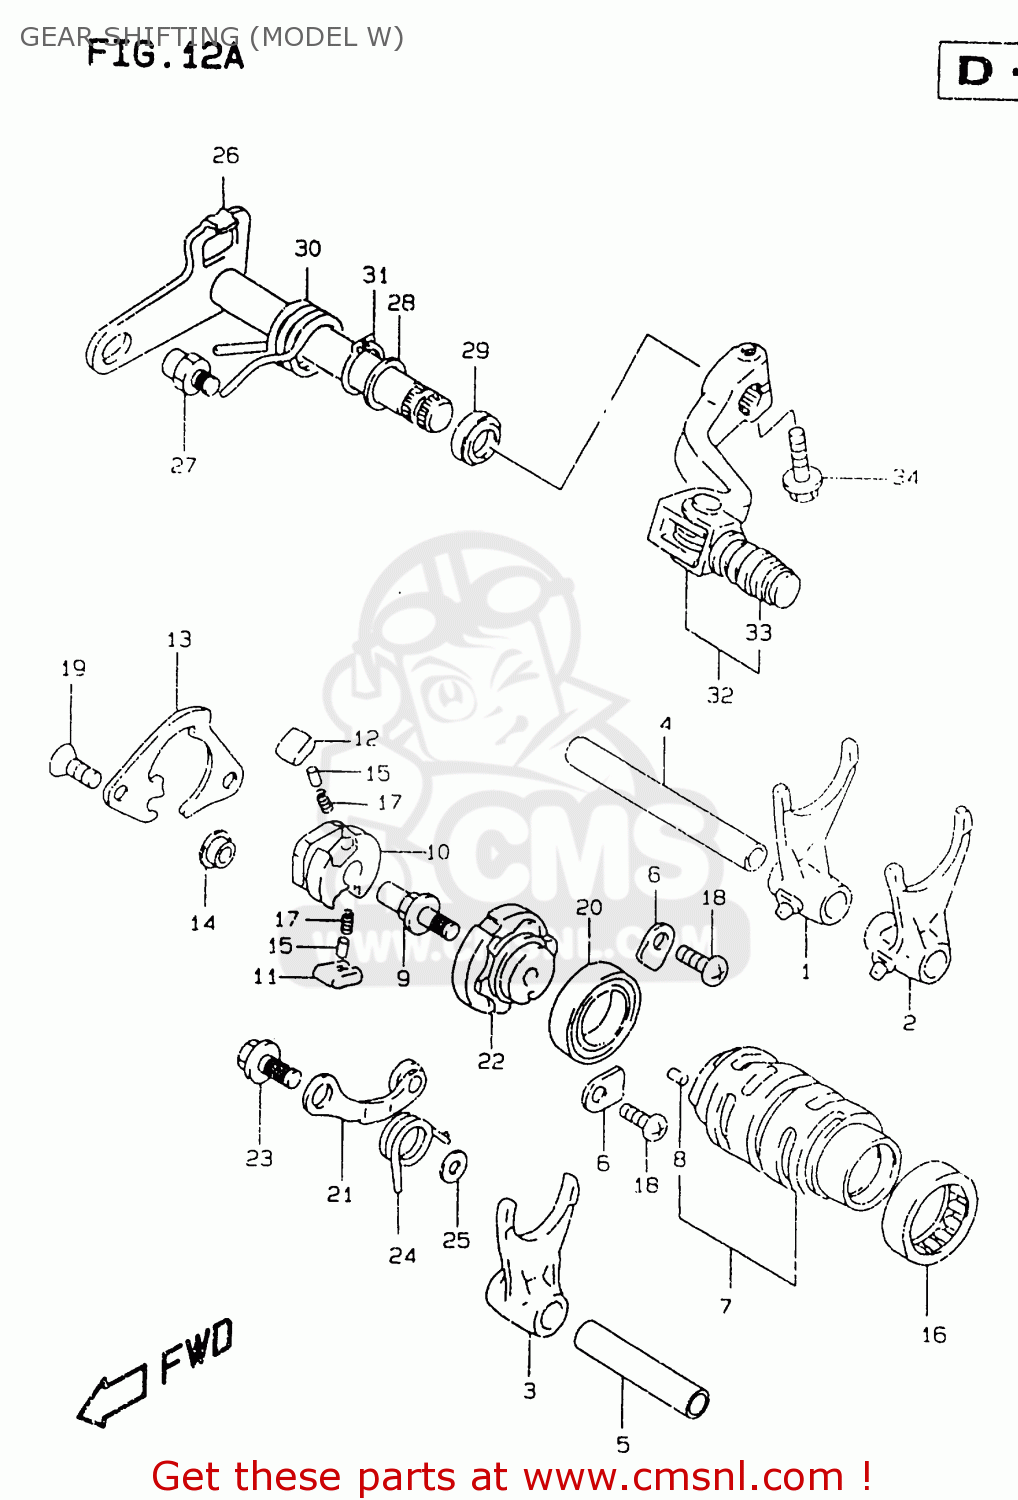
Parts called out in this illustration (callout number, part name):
1	FORK,GEAR SHIFT NO.1
2	FORK,GEAR SHIFT NO.2
3	FORK,GEAR SHIFT NO.3
4	SHAFT,GEAR SHIFT FORK
5	SHAFT,GEAR SHIFT FORK
6	RETAINER
7	CAM,GEAR SHIFT
8	PIN
9	PIN,SHIFT CAM DRIVEN GEAR
10	SHIFTER,GEAR SHIFT CAM
11	PAWL,GEAR SHIFT NO.1
12	PAWL,GEAR SHIFT NO.2
13	LIFTER,GEAR SHIFT PAWL
14	SPACER(7X10X5)
15	PIN(5X8)
16	BEARING(33X38X8)
17	SPRING
18	SCREW
19	SCREW
20	BEARING
21	STOPPER,SHIFT CAM
22	PLATE,SHIFT CAM STOPPER
23	BOLT(6X14.3)
24	SPRING
25	WASHER
26	SHAFT,GEAR SHIFT
27	STOPPER,SHIFT ARM
28	SHIM(14X20X1)
29	SEAL,OIL(14X22X6)
30	SPRING
31	CIRCLIP
32	LEVER ASSEMBLY,GEAR SHIFTING
33	RUBBER,GEAR SHIFT PEDAL
34	SCREW
